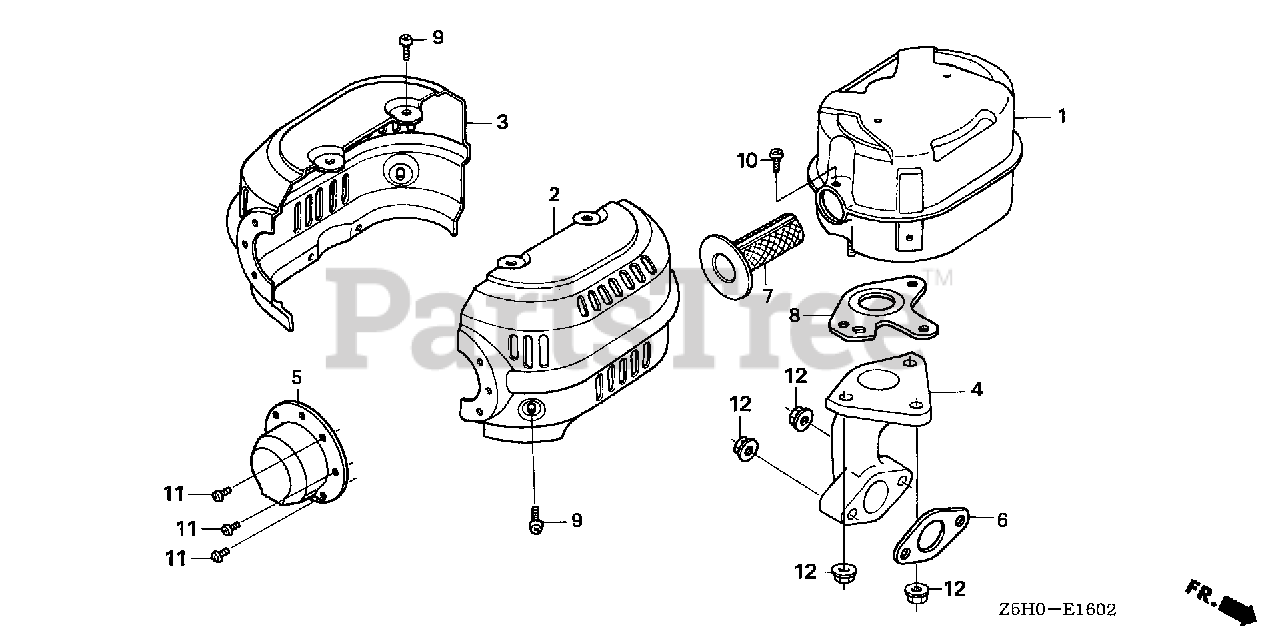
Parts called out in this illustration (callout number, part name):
1	MUFFLER
2	PROTECTOR, R. MUFFLER (STD)
3	PROTECTOR, L. MUFFLER (STD)
4	PIPE, EX.
5	CAP, MUFFLER
6	GASKET, EX. PIPE Use up to Engine SN 2949254.
6	GASKET, EX. PIPE (WACKER)
7	ARRESTER, SPARK
8	GASKET, MUFFLER (ARRESTER)
9	SCREW, TAPPING (5X8)
10	SCREW, TAPPING (5X8)
10	SCREW, TAPPING (4X6) (TO INSTALL OPTIONAL SPARK ARRESTER)
11	SCREW, TAPPING (4X6) (TO INSTALL OPTIONAL SPARK ARRESTER)
12	NUT, FLANGE (8MM)
